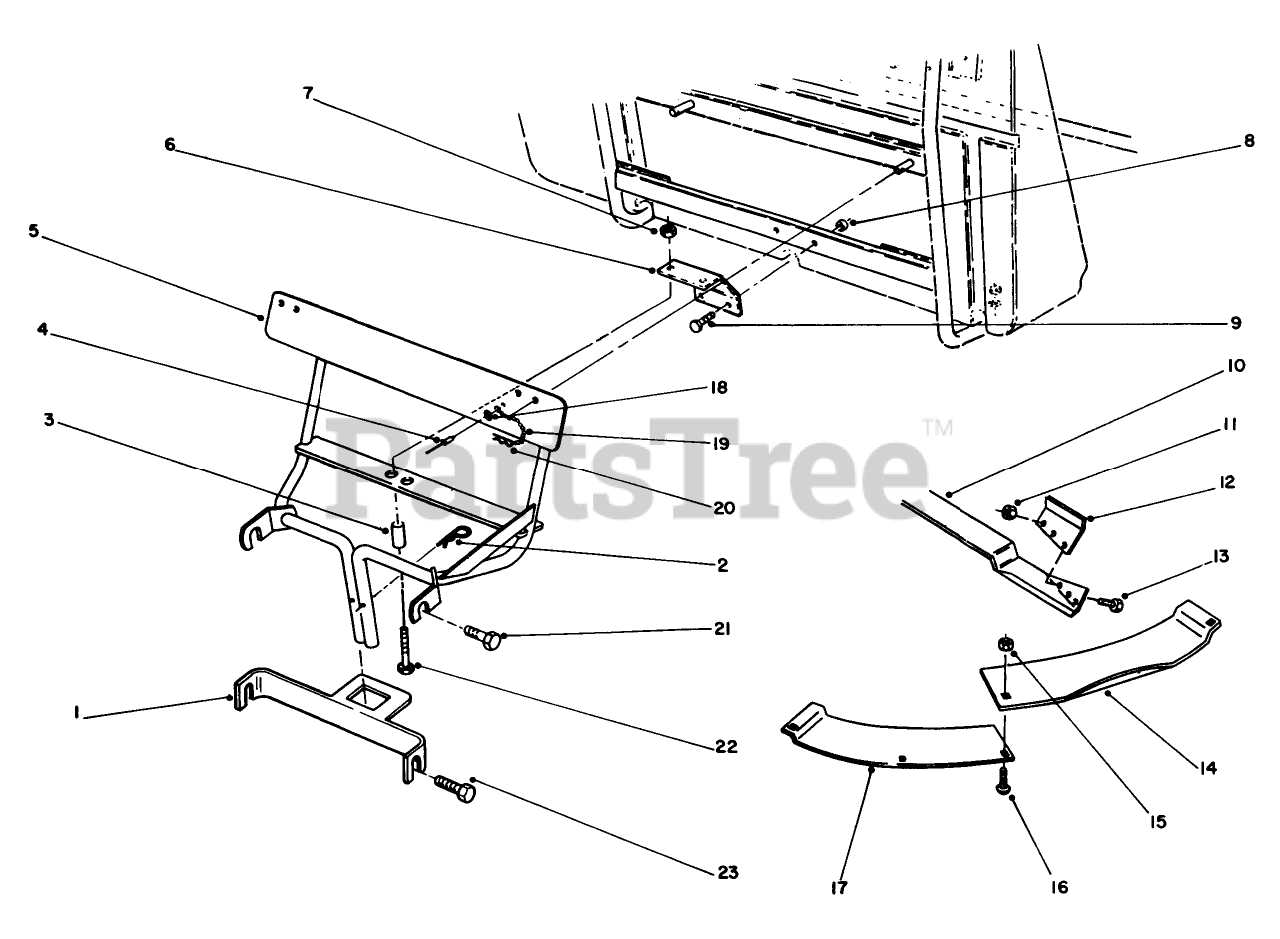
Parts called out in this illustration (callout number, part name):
2	Hairpin
4	Rivet-Pop
5	WLDMT-QUICK ATTAC *B
7	NUT-LOCK, NI
8	NUT-LOCK, NI
9	SCREW-HH
10	Blade (Ref.)
11	NUT-HEX
12	S/A LIFT TAB KIT
13	BOLT 5/16-18X5/8
14	PLATE MOWER *B
15	NUT-LOCK, NI
18	WASHER
20	Hairpin
21	SCREW-HH
